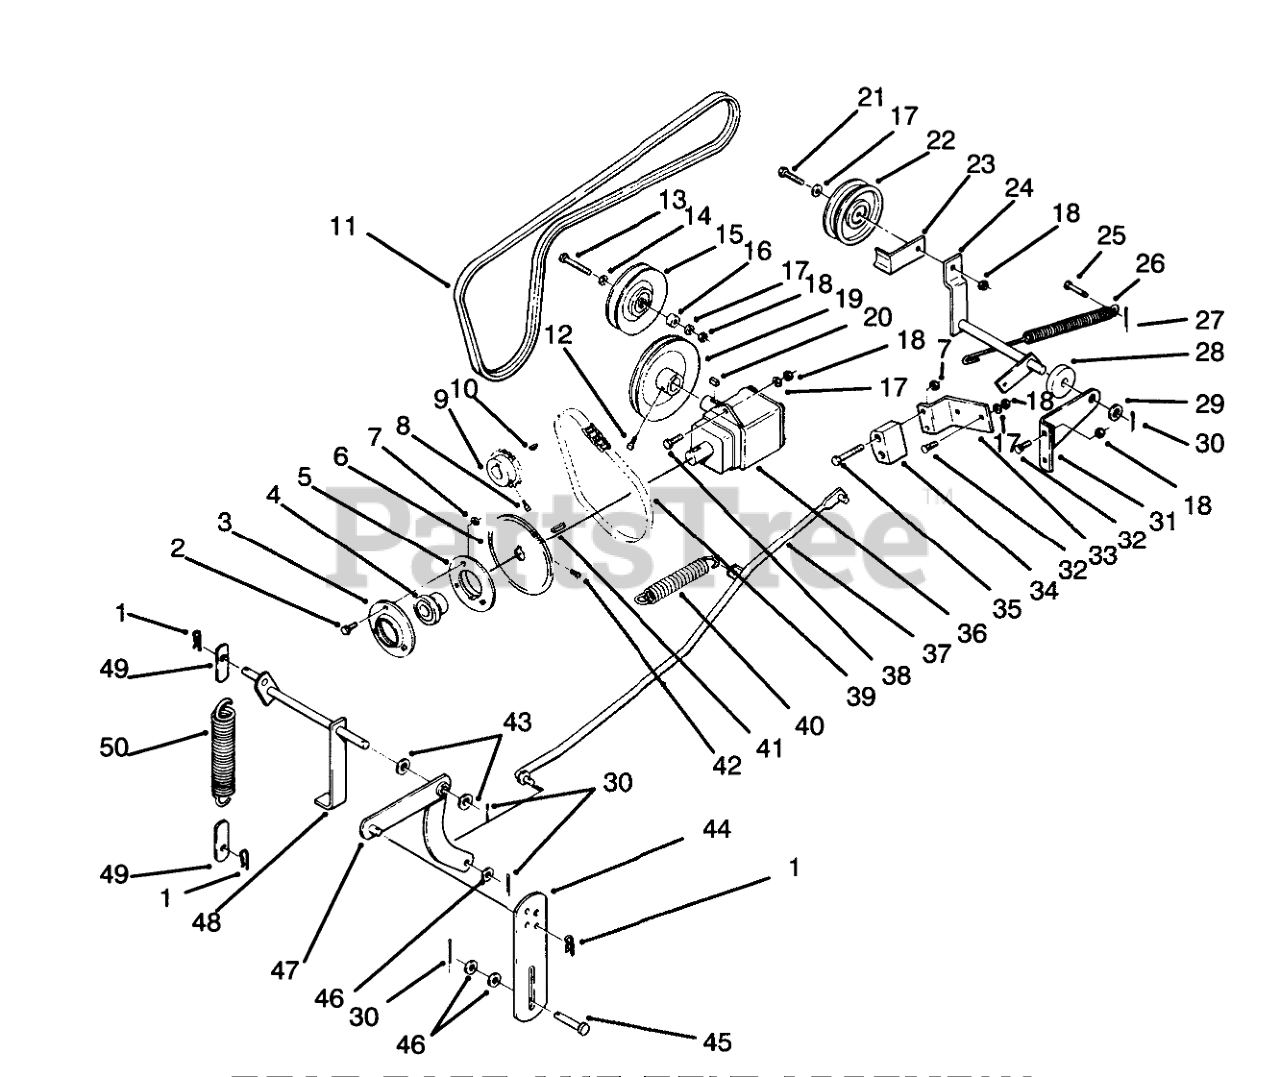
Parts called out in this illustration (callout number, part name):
1	Hairpin Cotter
2	BOLT-CARR
3	Flange
4	BEARING AND COLLAR
5	FLANGE-RELUBE
6	SPROCKET-33T
7	NUT-LOCK, NI
8	SCREW-SET
9	SPROCKET-15 T
10	KEY-HI PRO
11	V-BELT 64 .5EL
12	SCREW-SQH
13	SCREW-HH
14	WASHER
15	PULLEY-IDLER
16	SPACER
17	WASHER-FLAT
18	NUT-LOCK, NI
19	PULLEY - GEAR BOX
20	KEY-WOODRUFF
21	SCREW-HH
22	PULLEY-FLAT IDLER
23	Spacer
24	WLDMT-IDLER ARM R
25	PIN-CLEVIS
26	SPRING
27	PIN-COTTER
28	RUBBER WASHER
29	WASHER-FLAT
30	PIN-COTTER
31	BRACKET-PIVOT R
32	BOLT-CARR
33	BRACKET-TIGHTENER R
34	Chain Tightener
35	SCREW-HH
36	GEAR-BOX L.H.
37	WLDMT-LIFT ROD R
38	BOLT-CARR
39	CHAIN
40	SPRING
41	KEY
42	SCREW-SET, SQH
43	WASHER
44	LINK-LIFT R
45	CLEVIS PIN
46	WASHER-FLAT
47	WLDMT-SNOWTHWR LI R
48	WLDMT-SPRING SUPP R
49	RETAINER-SPRING R
50	SPRING
